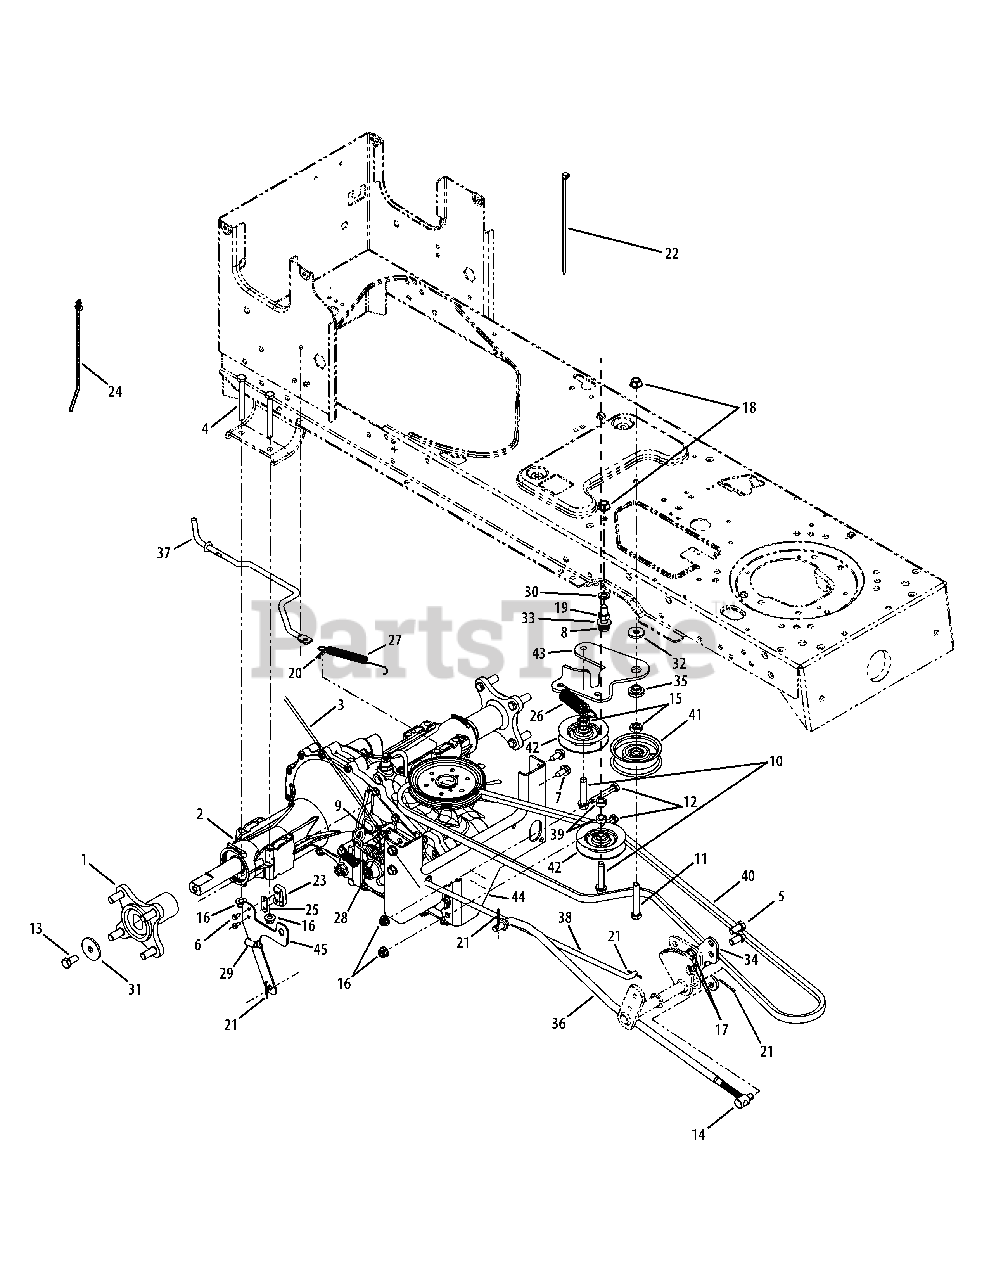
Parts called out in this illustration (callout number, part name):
1	Hub Assembly
2	Transmission, Hydrostatic
3	Wire Harness, Reverse
4	Screw, Hex Cap, 5/16-18 x 3.00 Gr5
5	Screw, Hex Cap, 3/8-16 x .75 Gr5
6	Screw, Hex Wash Hd Tapp, #8-18 x .5
7	Screw, Hex Cap, 5/16-18 x .750
8	Screw, Hex Cap, 3/8-16 x 1.50 Gr5
9	Screw, Self-Tapp, 1/4-20 x .5
10	Sems Screw, 3/8-16 x 1.875
11	Hex Cap Screw, 3/8-16 x 2.25, Gr5
12	Screw, Hex Cap, 5/16-18 x 2.00
13	Screw, Hex Cap Lock, 3/8-16 x .75
14	Ferrule, 3/8-24 x .375 Dia
15	Jam Nut, 7/16-20
16	Nut, Flange Insert Lock, 5/16-18 Gr5
17	Nut, Flange Insert Lock, 3/8-16 GrF
18	Nut, Flange Insert Lock, 3/8-16 GrF
19	Nut, Hex, 3/8-16, GR5
20	Pin, Cotter, .072 Dia. x 1.13
21	Pin, Cotter, 3/32, 1.0
22	Cable, Tie, 3/16 x .05 x 7.4
23	Switch, Spring, Short
24	Tie, Cable, Push Mount 7.5
25	Plate, Insulator Nut
26	Spring, Extension, .77 Dia x 3.7 Lg
27	Spring, Extension, .50 OD x 5.00 Lg
28	Spring, Extension, .59 OD x 4.00 Lg
29	Spring, Extension, 3/8 OD x 1.44 Lg
30	Washer, Lock, 3/8 , Regular Duty
31	Washer, Flat, .390 x 1.50 x .134
32	Washer, Flat, .385 x 1.0 x .135
33	Washer, Flat, .406 x .875 x .059
36	Rod, Hydro Control
37	Rod, Hydro Disengage
38	Rod, Brake
39	Spacer, .380 x .625 x .265
40	Belt, V-Type
41	Pulley, Idler, Flat 2.75 OD
42	Pulley, Idler, Flat 3.06 OD
